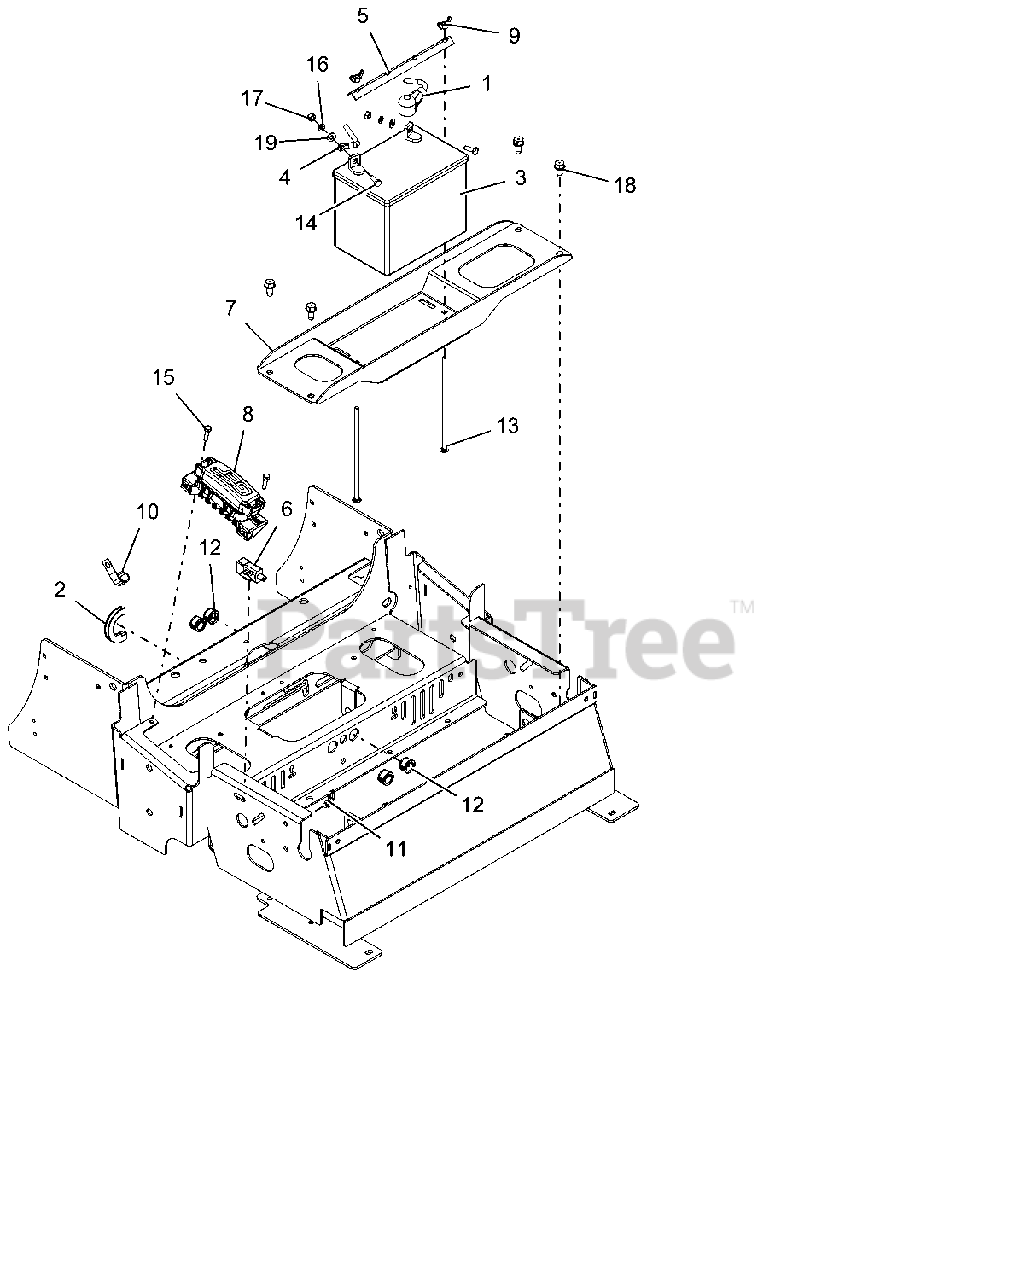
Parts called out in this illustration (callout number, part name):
1	CABLE, POS BATT W/ BOOTS 6 X 35
2	STRIP, COWL - 1.50 LG
3	BATTERY, 300 CCA 10U1L
4	CABLE, NEGATIVE BATTERY 35.00"
5	HOLD DOWN - BLK
6	SWITCH, SNAP IN -N.O./N.O
7	TRAY, BATTERY-RED
8	HARNESS, PT200/400 WIRING
9	NUT-LOCKING WING 1/4-20
11	CABLE TIE W/ TREE (.25 HOLE)
12	BUSH, PANEL SNAP .687X.875X.56
13	BLT-RDHDSQNK .25-20X7.50 G2 YWZC
14	BLT-HEX .25-20X.75 GR5 YWZC
15	@BLT-HEX M6-1.0X25 YWZC
16	WSHR-LK .25X.062 REG YWZC
17	NUT-HEX .25-20 YWZC
18	SCR-TAP .38-16X.75 HWH TR YWZ
19	WSHR-FL-STL.281X.62X.065 YWZC
